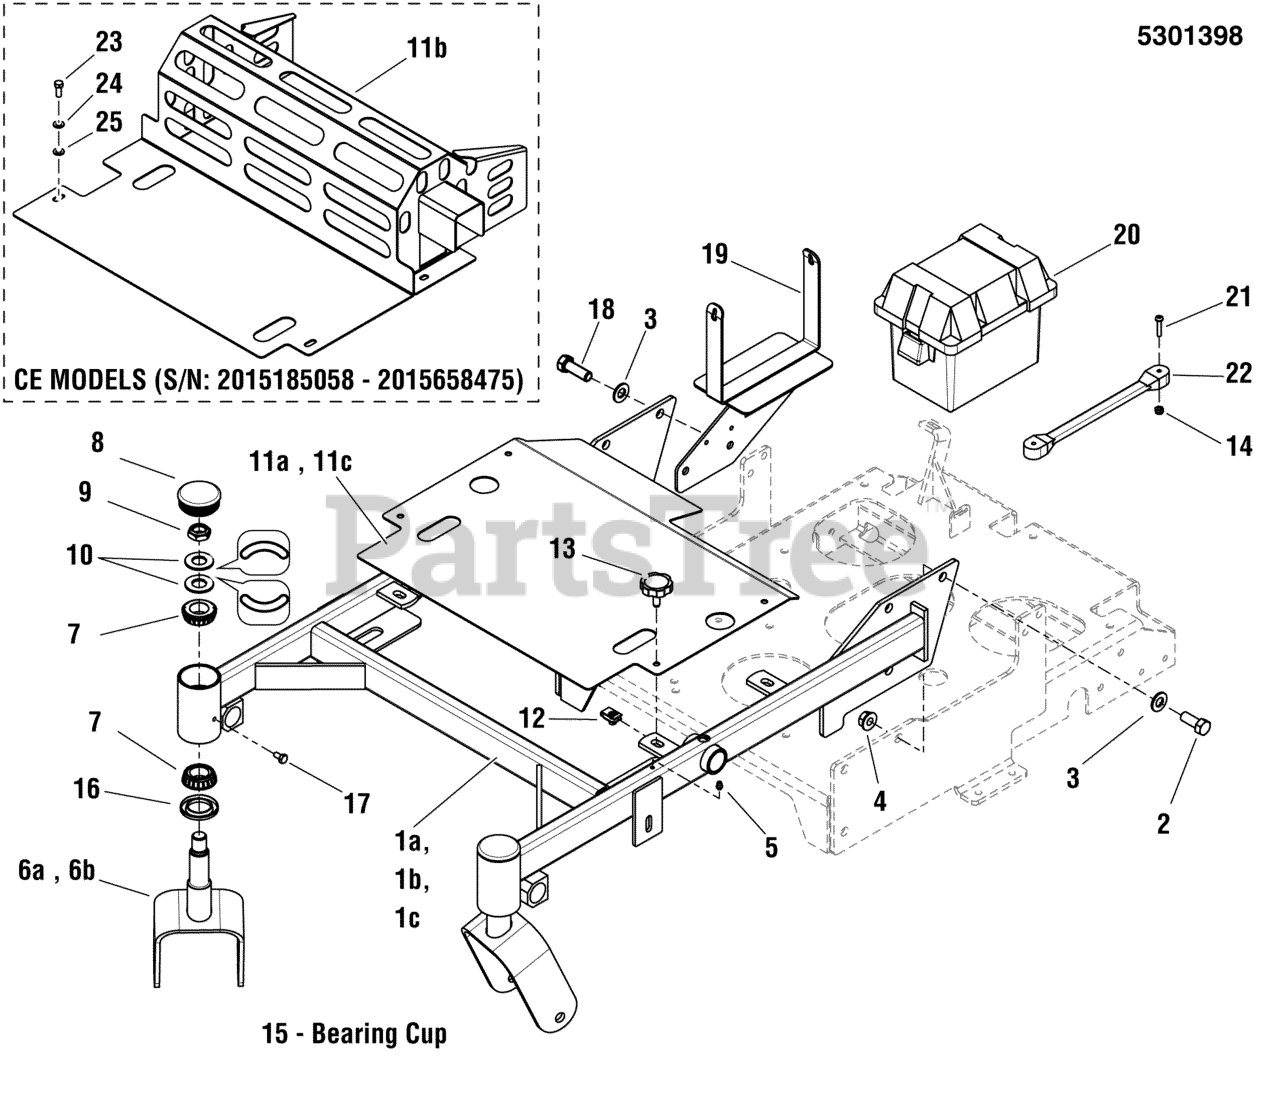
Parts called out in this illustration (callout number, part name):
2	BOLT, 1/2-13 X 1-1/2 GD5 CZ
3	WASHER, 1/2 SAE
4	NUT, Hex Flange, Nylock, 1/2-13
5	GREASE FITTING, 1/4-28 STRAIGHT
7	BEARING, TAPERED ROLLER, 1
8	CAP, GREASE, LOW PROFILE
9	NUT, 3/4-16, HEX JAM NYLON LOCK
10	WASHER, BELLEVILLE - 1.500 X .755
12	BODY CLIP, 5/16-18 -1/4 MATERIAL
13	KNOB, 5/16-18 X 1.00, ROSETTE BLACK
14	NUT, #10-24 HEX NYLON LOCK
16	SEAL, GREASE
17	BOLT, 1/4-28 X 1/2, GD5 YZ
18	BOLT, 1/2-13 X 1-3/4 GD5 CZ
19	WELD, BATTERY MOUNT - RED
20	BATTERY BOX, W/ DRAIN HOLE
21	SCREW, #10-24 X 1 RS, CZ
22	STRAP, RUBBER
23	BOLT, 5/16-18 X 1 GD5 YZ
24	WASHER, 5/16 LOCK CZ
25	WASHER, 5/16" SAE
